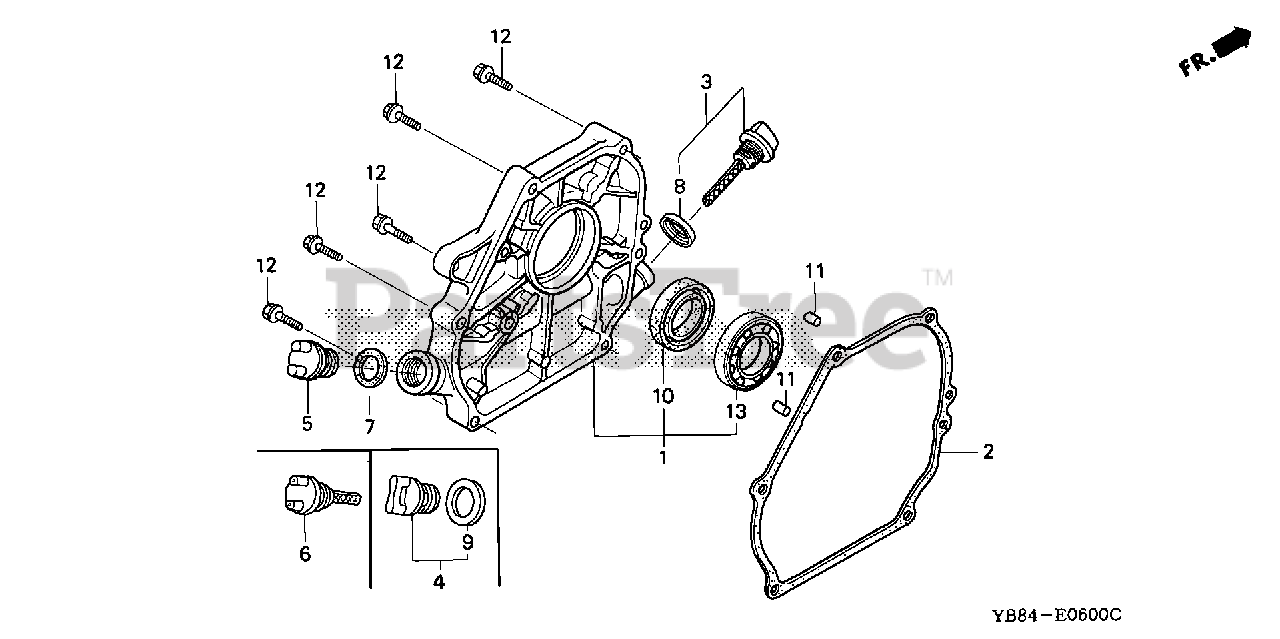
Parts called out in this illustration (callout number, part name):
1	COVER ASSY., CRANKCASE
2	GASKET, CASE COVER (NON-ASBESTOS)
3	CAP ASSY., OIL FILLER
4	CAP ASSY., OIL FILLER
8	GASKET, OIL FILLER CAP
9	GASKET, OIL FILLER CAP
10	OIL SEAL (25X41X6)
11	PIN A, DOWEL (8X14)
12	BOLT, FLANGE (8X32)
13	BEARING, RADIAL BALL (6205)
